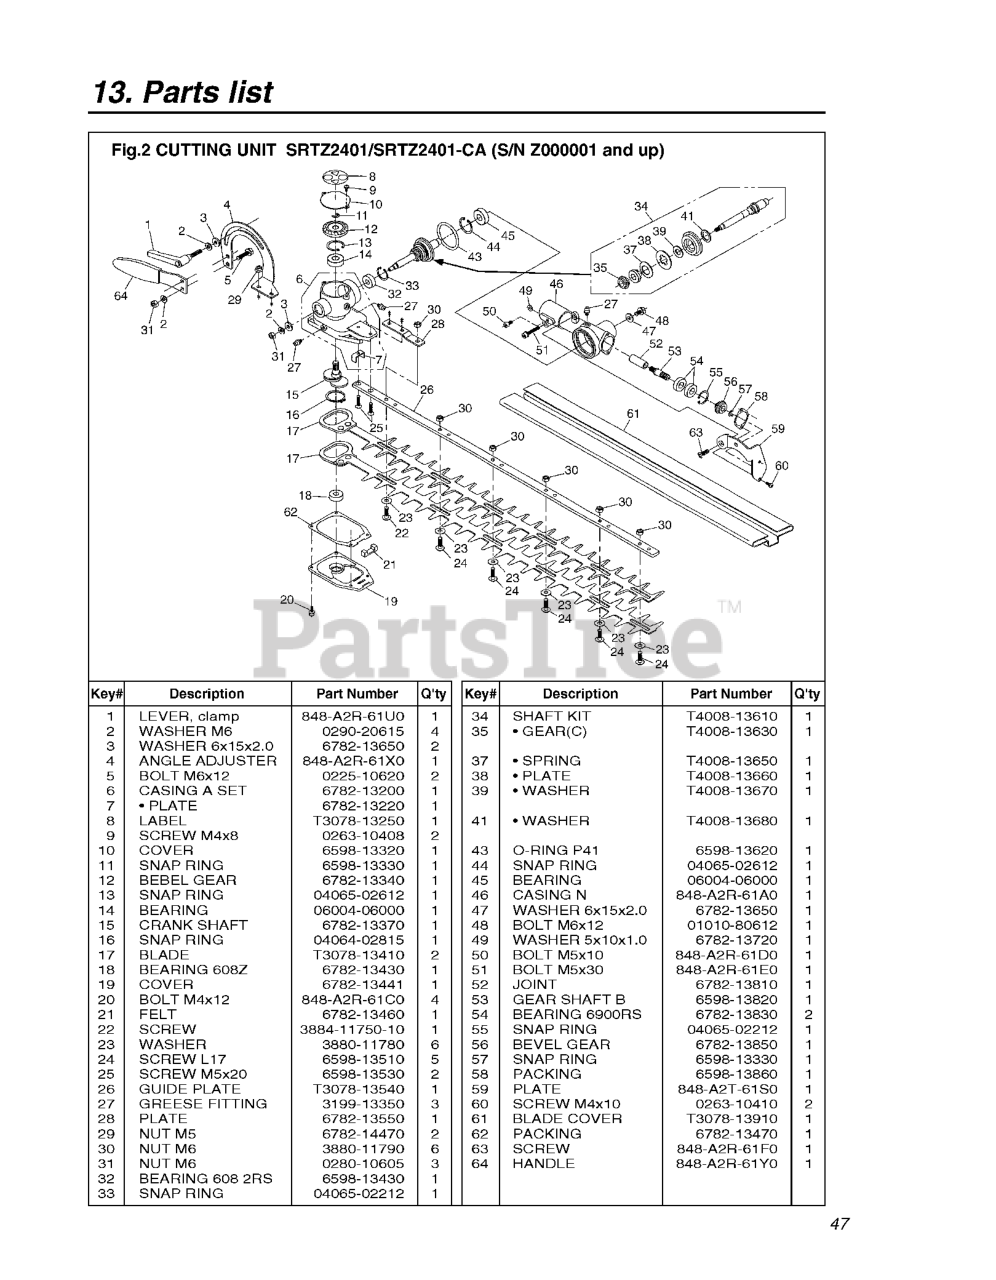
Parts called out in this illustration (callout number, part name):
1	CLAMP LEVER M6X16MM
4	ANGLE ADJUSTER
6	CASE(A) SET
10	COVER(A)
13	RING,SNAP M26x1.2 RP-318013340
15	CRANKSHAFT
16	RING, SNAP, M28 x 1.5
17	BLADE, SRT, 24"
18	BEARING
22	SCREW(R3873,388411750&11770
24	SCREW.L17
25	SCREW.5X20
26	PLATE, GUIDE
29	RP_NUT
33	RING, SNAP, M22 x 1.2
34	SHAFT
35	GEAR (C)
37	WASHER, SPRING
44	RING,SNAP M26x1.2 RP-318013340
46	CASING N***
48	BOLT M6x12 (RPLS 022510612)
50	BOLT M5X10
51	BOLT M5X30
53	GEARSHAFT(B)
55	RING, SNAP, M22 x 1.2
61	COVER, BLADE
